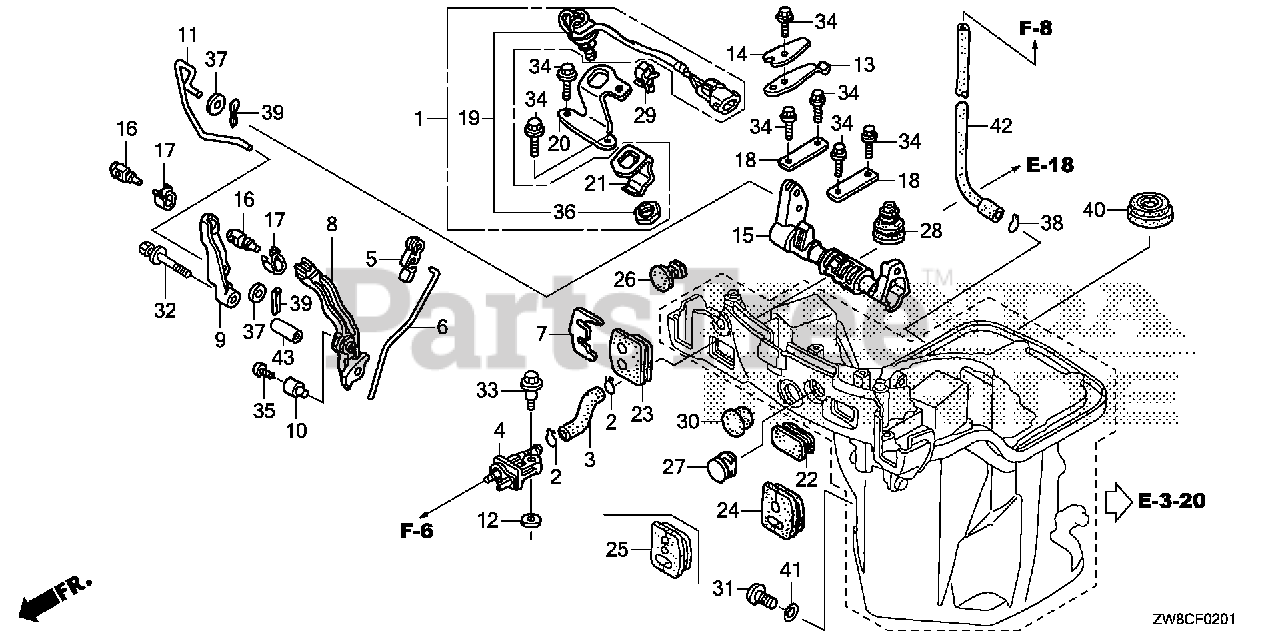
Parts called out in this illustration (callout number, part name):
1	SWITCH SET, NEUTRAL
2	CLIP, TUBE
3	TUBE A, FUEL (FKM)
4	CONNECTOR ASSY., FUEL (B)
5	LINKAGE, PIVOT
6	ROD, THROTTLE
7	PLATE, REMOTE CONTROL CABLE
8	ARM, THROTTLE REMOTE
9	ARM, SHIFT LINK
10	HOLDER, THROTTLE ROD
11	ROD, SHIFT LINK
12	WASHER, PIVOT
13	SPRING, CLICK
14	SPRING, CLICK ASSIST
15	SHAFT, SHIFT
16	PIVOT, SHIFT
17	PLATE, LOCK
18	PLATE, SHIFT SHAFT
19	SWITCH ASSY., NEUTRAL
20	BRACKET, NEUTRAL SWITCH
21	PLATE, NEUTRAL SWITCH
22	GROMMET G, OIL CASE
23	GROMMET A, OIL CASE
25	GROMMET B, OIL CASE (PT)
26	GROMMET F, OIL CASE
27	GROMMET D, OIL CASE
28	GROMMET E, OIL CASE
29	CLIP, BRAKE PIPE (A)
30	CAP, HANDLE (LOWER)
31	BOLT, OIL CHECK
32	BOLT-WASHER (6X40)
33	BOLT, SPECIAL (6X22) (CT200)
34	BOLT, FLANGE (5X12) (CT200)
35	BOLT, RECESSED (5X8)
36	NUT, HEX. (20MM)
37	WASHER, PLAIN (7MM)
38	CLIP, TUBE (B10)
39	PIN, SPLIT (2.0)
40	SEAL, WATER (13X28X7)
41	O-RING (6.9X1.45)
42	TUBE, WATER CHECK
43	COLLAR, DISTANCE (6X11X27)
